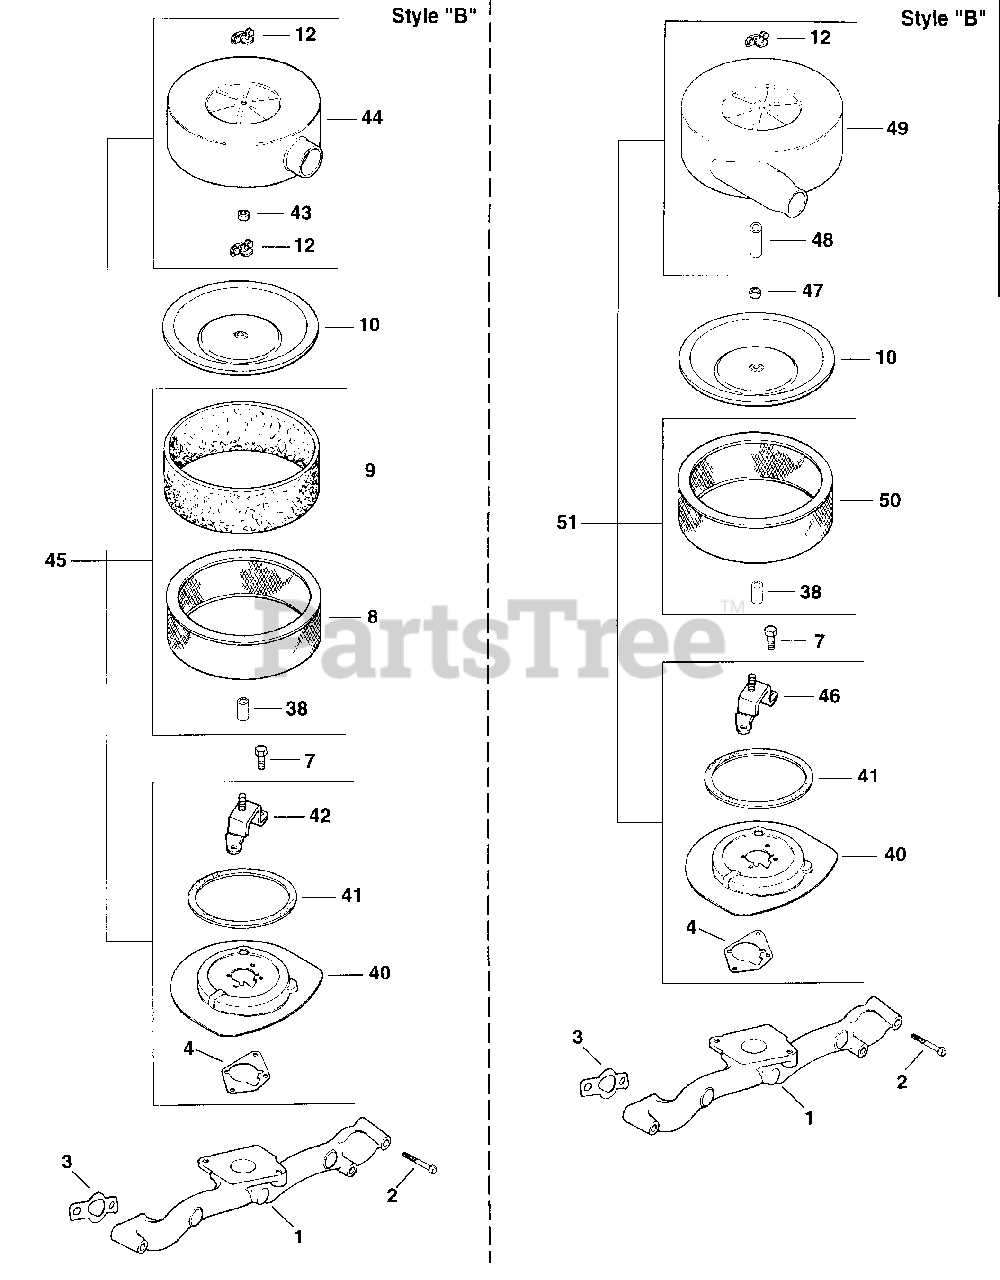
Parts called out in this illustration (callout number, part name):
1	MANIFOLD, METAL INTAKE
2	Screw, hex. flange M6x1.0x55
3	GASKET, INTAKE MANIFOLD USE 24 041 79-S
4	GASKET, AIR CLEANER BASE
7	SCREW - USE M-639016
8	ELEMENT, AIR CLEANER - Also available Retail Packaged 47 883 03-S1 Air Filter Kit
9	ELEMENT, PRECLEANER (LOW)
10	COVER, INNER AIR CLEANER
12	NUT, WING
38	SEAL, BREATHER
40	BASE, AIR CLEANER-USE 24 094 91-S
41	KIT - USE 24 743 18
42	BRACKET, AIR CLEANER-USE 24 126 207-S
44	COVER - USE 24 096 52
45	KIT, DOME AIR CLEANER
